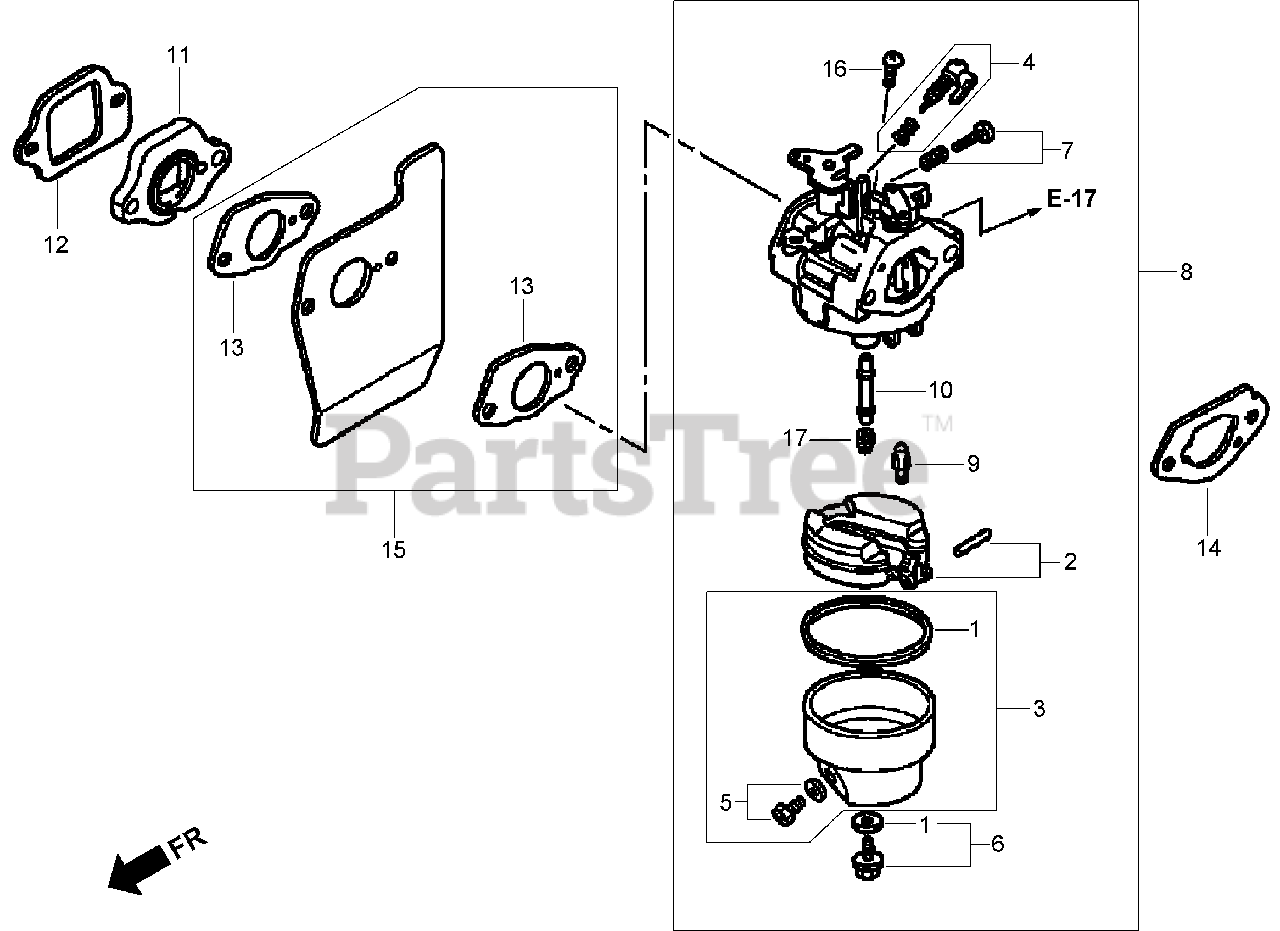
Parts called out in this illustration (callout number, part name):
1	GASKET SET
2	FLOAT SET
3	FLOAT CHAMBER SET
4	SCREW SET
5	DRAIN SCREW SET
6	SCREW SET
7	SCREW SET (THROTTLE STOP)
8	CARBURETOR ASM (BB65G A)
9	VALVE-FLOAT
10	NOZZLE-MAIN
11	INSULATOR-CARBURETOR
12	GASKET-INSULATOR
13	GASKET-CARBURETOR
14	GASKET-CARBURETOR
15	GUIDE-AIR
16	SCREW-PAN (5X6)
17	JET-MAIN (No.62)
17	JET-MAIN (No.65)
17	JET-MAIN (No.68)
